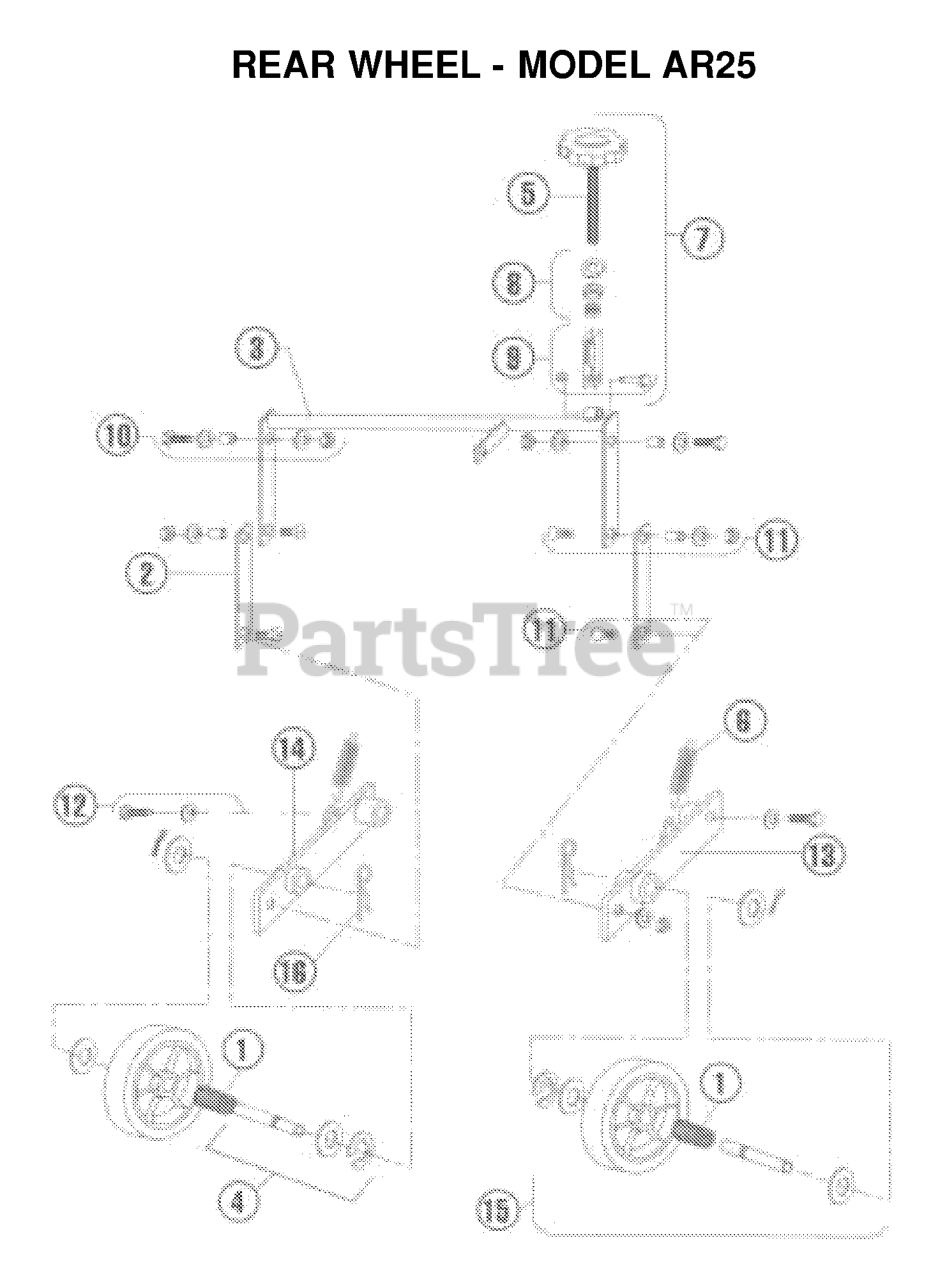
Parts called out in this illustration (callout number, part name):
1	BEARING, ROLLER
2	LIFT ARM LINK LWR ORN
3	KIT, TORQUE ARM
4	AXLE KIT
5	KNOB, DEPTH/STABILITY
6	SPRING, IDLER CAM, 3 3/4"
7	KIT DEPTH CONTROL STABILITY
8	KNOB SPRING KIT
9	BRACKET KIT
10	FASTENER KIT
11	FASTENER KIT, LINKAGE
12	FASTENER KIT
13	WHEEL ARM
14	WHEEL ARM
15	REAR WHEEL, COMPLETE
16	COTTER KEY
